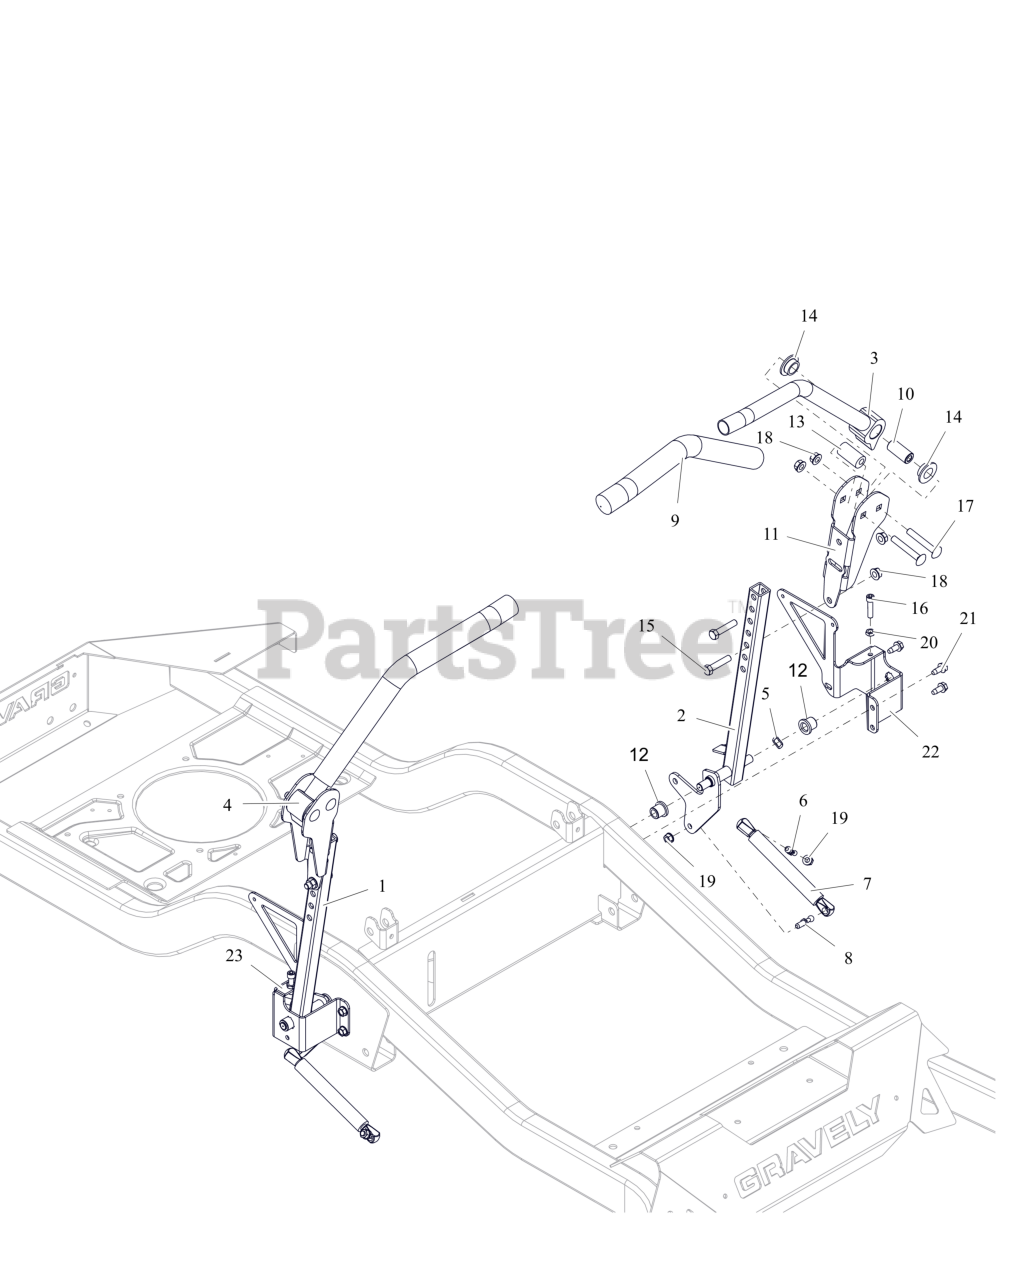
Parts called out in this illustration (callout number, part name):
1	WLDMT, STEERING RH (RED)
2	WLDMT, STEERING -LH (RED)
3	WLDMT, CONTROL HANDLE (RED)
4	WLDMT, CONTROL HANDLE (RED)
5	WAVE WASHER .531X.781X.125FH
6	STUD- BALL
7	DAMPER
8	STUD-BALL-THREADED
9	GRIP, HANDLEBAR
10	SPACER, STEERING ARM
11	BRKT, ADJ UPPER CONTROL ARM (RED)
12	BHSG-FLG .500X.750X.750X.125
13	BSHG, ECCENTRIC.406X.875X1.625
14	BSHG-FLG .762X1.48X.44 NYL
15	BLT, HEX .38-16X1.75 G5 ZCC
16	SCR, SKH .312-18X1.25 GR8 ZC120
17	BLT, RHSSN.38-16X2.50 G5 ZCC
18	NUT-LK-TOP-FLG .38-16 ZC120
19	NUT,LK-CTR-FLG .31-18 GF ZCC
20	NUT-JAM .312-18 G2 ZCC
21	SCR,TAP .312-18X.75 HWH TR ZCC
22	BRKT, STEERING ARM MOUNTING -LH (RED)
23	BRKT, STEERING ARM MOUNTING- RH (RED)
